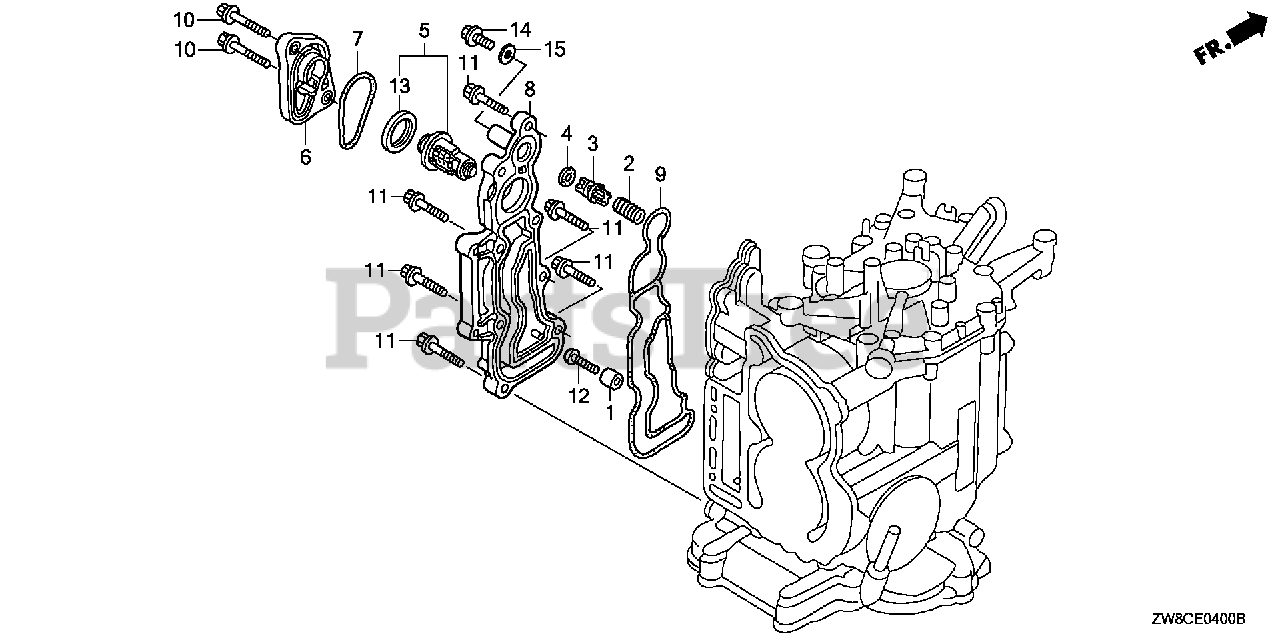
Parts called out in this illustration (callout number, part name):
1	METAL, ANODE
2	SPRING, FLUSH VALVE
3	VALVE, FLUSH
4	GASKET, FLUSH VALVE
5	THERMOSTAT ASSY.
6	COVER, THERMOSTAT
7	O-RING, THERMOSTAT COVER
8	COVER, WATER JACKET
9	GASKET, EX. WATER JACKET COVER
10	BOLT, FLANGE (6X36) (CT200)
10	BOLT (6X36) (CT200)
11	BOLT, FLANGE (6X22) (CT200)
12	BOLT, FLANGE (5X20)
12	SCREW, PAN (5X20)
13	RUBBER, RING
14	BOLT, SPECIAL (8MM)
15	GASKET (8MM)
